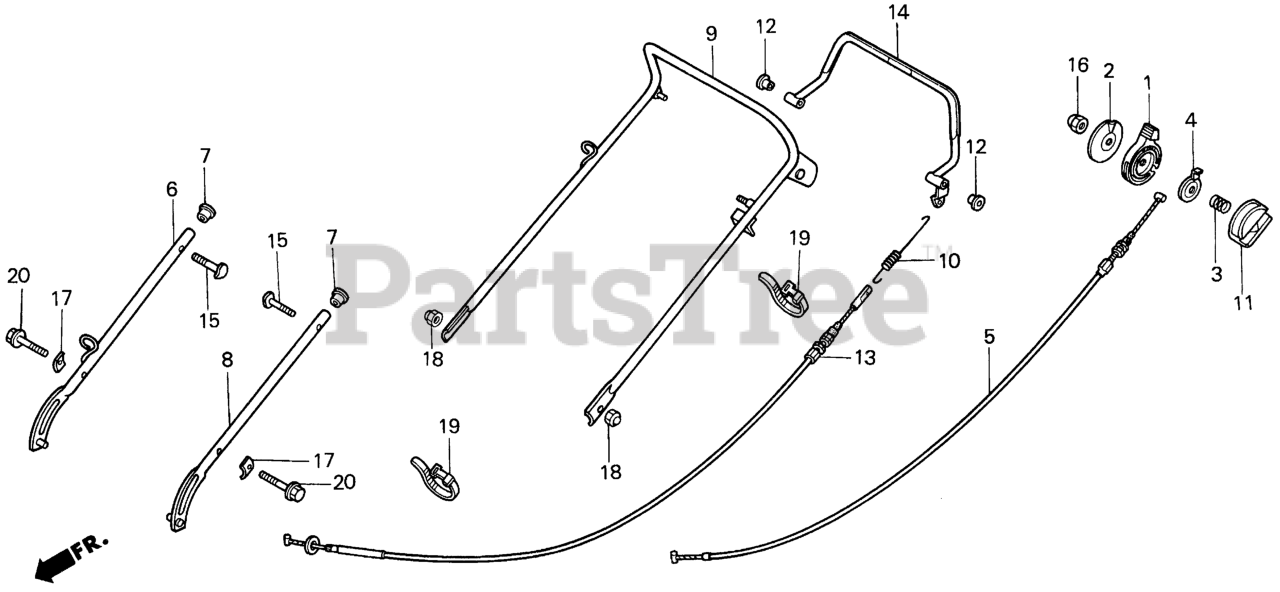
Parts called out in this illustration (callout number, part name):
1	LEVER, THROTTLE
2	PLATE, THROTTLE LEVER
3	SPRING, THROTTLE LEVER
4	SEAT, SPRING
5	CABLE, THROTTLE
6	PIPE, R. HANDLE (LOWER)
7	CAP, HANDLE (LOWER)
8	PIPE, L. HANDLE (LOWER)
9	PIPE, HANDLE (UPPER) (NOT AVAILABLE)
10	SPRING, BRAKE
11	COVER, CONTROL
12	BUSH, CLUTCH LEVER
13	CABLE, BRAKE
14	LEVER, BRAKE (NOT AVAILABLE)
15	BOLT, HANDLE HOLDER (NOT AVAILABLE)
16	NUT, CAP (6MM)
16	NUT, FLANGE (6MM)
17	WASHER, FRAME JOINT
18	NUT, CAP (8MM)
19	BAND B1, CABLE
19	TIE, CABLE
20	BOLT, FLANGE (8X40)
